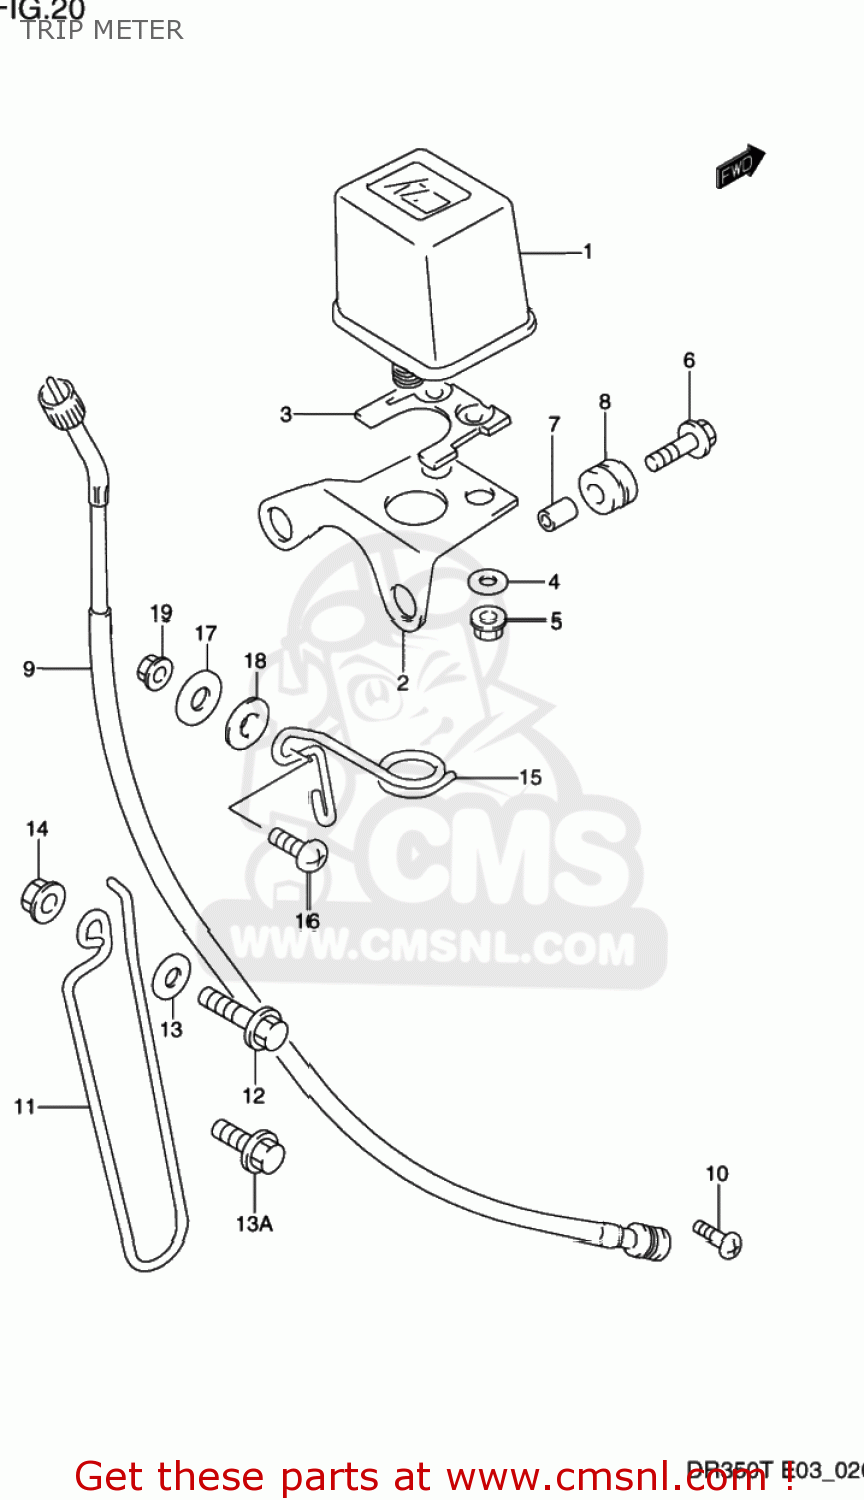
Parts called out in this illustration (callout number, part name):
1	TRIP METER
2	BRACKET
3	CUSHION
4	WASHER,METER
5	NUT
6	BOLT(6X25)
7	SPACER (6.1X8X9.5)
8	CUSHION
9	CABLE ASSY,SPEEDOMETER
10	SCREW
11	GUIDE,METER CABLE NO.2
12	BOLT
13	WASHER
13A	BOLT(6X20)
14	NUT
15	GUIDE,METER CABLE NO.3
16	SCREW
17	WASHER
18	WASHER
19	NUT
